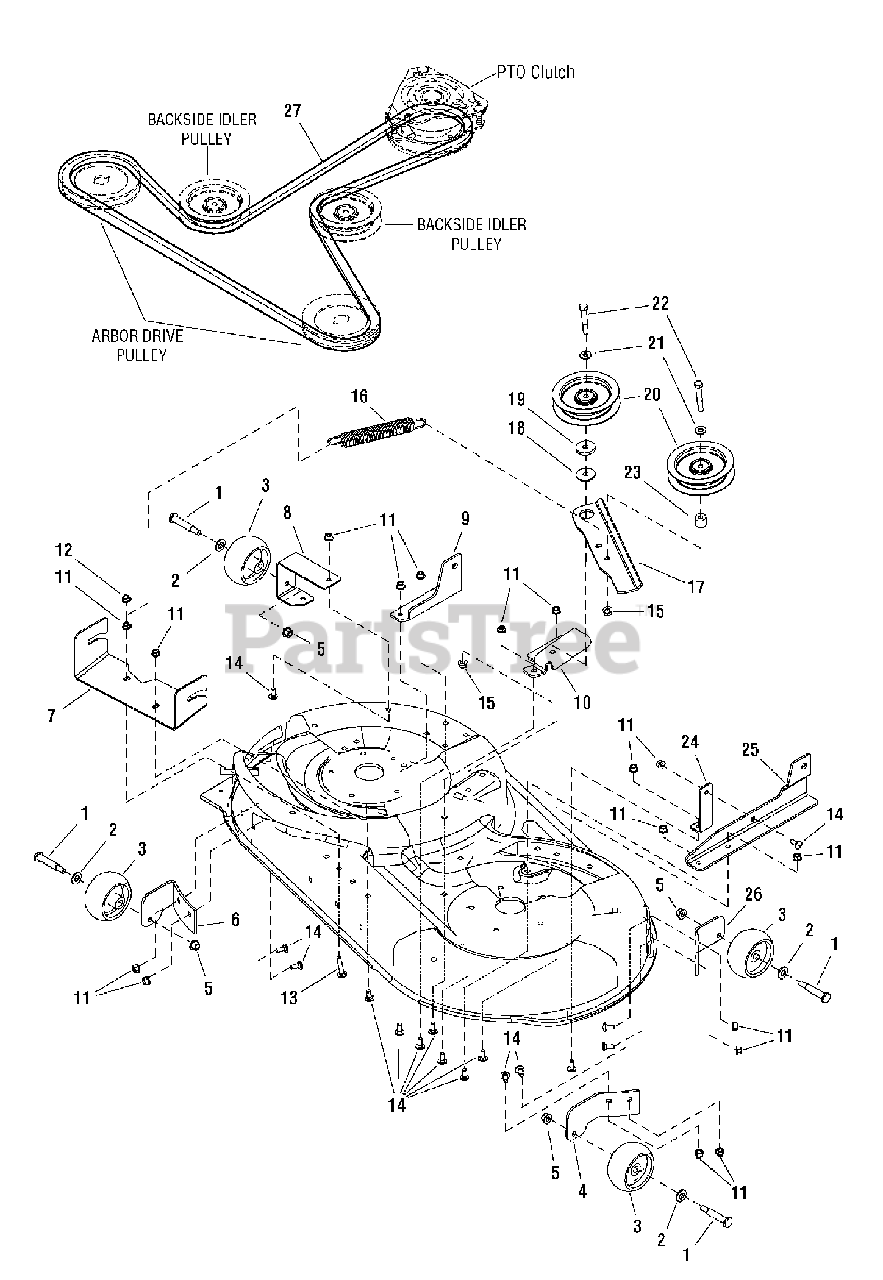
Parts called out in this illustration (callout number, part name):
1	BOLT, Wheel, 3/8-16 x 2.781
2	WASHER, .51 ID x 1 OD x 1/10 THK
3	GAUGE WHEEL
4	BRACKET, Gauge Wheel L.H. Front
5	NUT, Hex Flange, 3/8-16 ESNA
6	BRACKET, Gauge Wheel R.H. Front
7	HITCH, Mower Front
8	BRACKET, Gauge Wheel R.H. Rear
9	SUPPORT, Mower Rear R.H.
10	BRACKET, Fixed Idler
11	NUT, Hex Flange Whiz Lock, 5/16-18
12	NUT, Hex Two-Way Lock, 5/16-18
13	BOLT, Carriage 5/16-18 x 1.5, G5
14	BOLT, Carriage, 5/16-18 x 3/4, G5
15	NUT, Hex Flange Whiz Lock, 3/8-16
16	SPRING, Extension
17	ARM, Idler
18	SPACER, Powdered Metal
19	WASHER, 3/8, .41 ID x 1-1/2 OD x 1/4 THK
20	PULLEY, Idler, 4 OD x .378 ID x 1
21	WASHER, 3/8, .41 ID x .87 OD x .08 THK
22	CAPSCREW, Hex Head, 3/8-16 x 2-1/4, G5
24	BRACE, Mower Support
25	SUPPORT, Mower Rear L.H.
26	SUPPORT, Gauge Wheel, LH
27	V-BELT, A-Wedge
